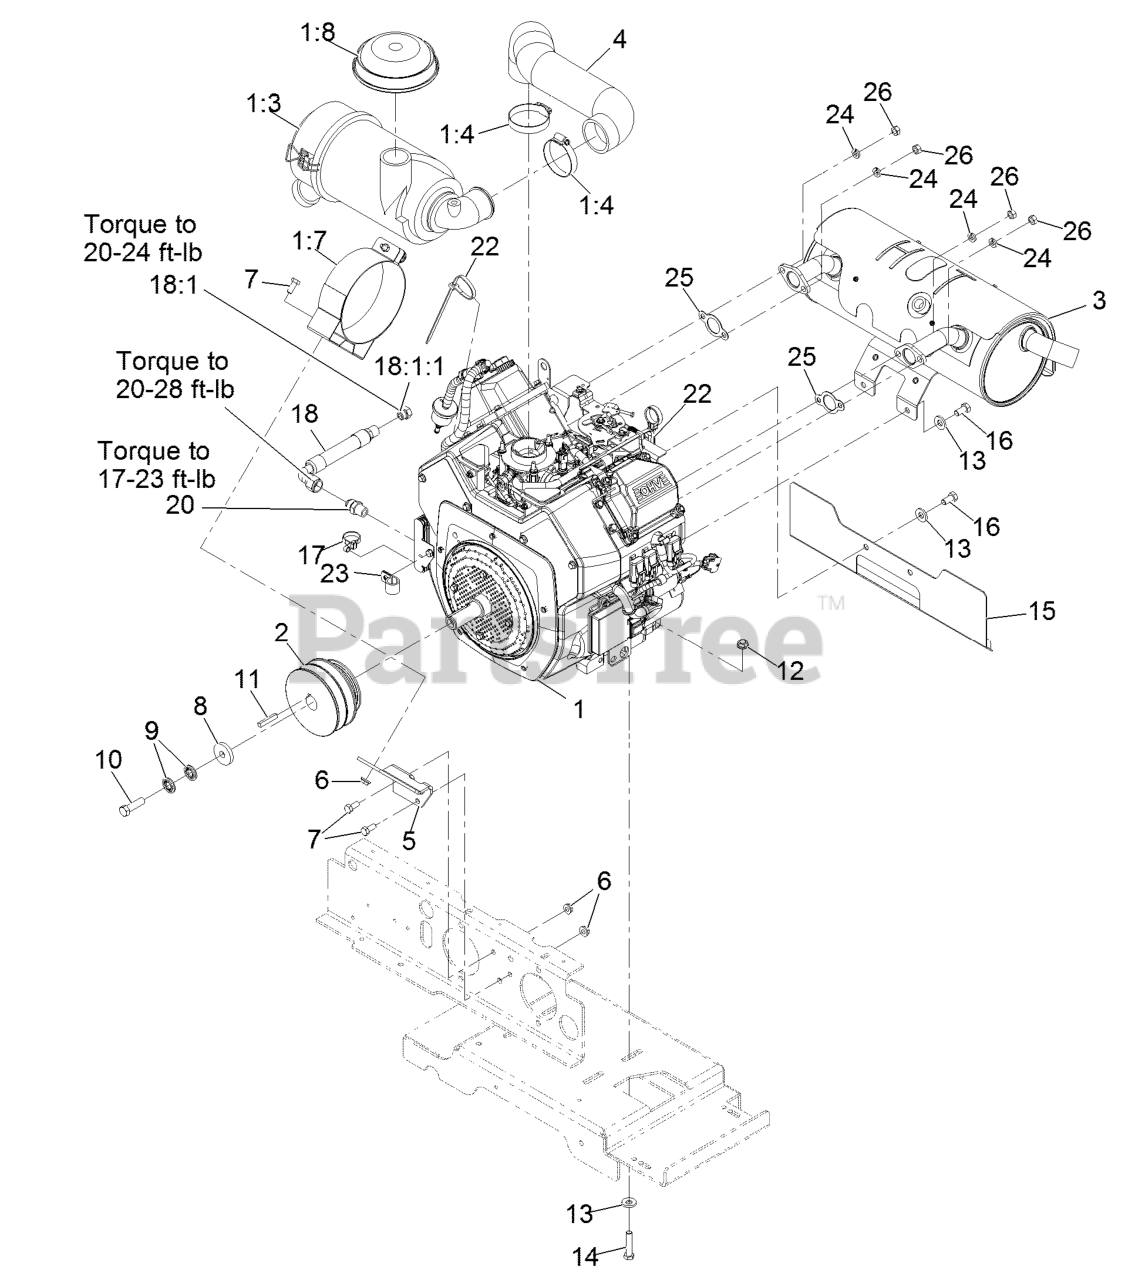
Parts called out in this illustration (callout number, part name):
1:3	AIR CLEANER CANISTER ASM
1:4	CLAMP-HOSE
1:7	BRACKET-FILTER, AIR
1:8	HOOD-CLEANER, 2" AIR INTA
4	HOSE-AIR INTAKE
5	BRACKET-FILTER, AIR
7	SCREW-HH
8	WASHER-CLUTCH
9	WASHER-SPRING
10	SCREW-HH
11	KEY-SQUARE
12	NUT-HHF, WHIZ
13	WASHER-BELLEVILLE
14	SCREW-HH
15	SHIELD-EXHAUST
16	SCREW-HH
17	Tie-Cable
18	OIL DRAIN HOSE ASM
18:1	PLUG-HH
18:1:1	O-RING
20	FITTING-STRAIGHT
22	TIE-PLASTIC
23	CLIP-LOOM
24	WASHER-LOCK
26	NUT-HEX
